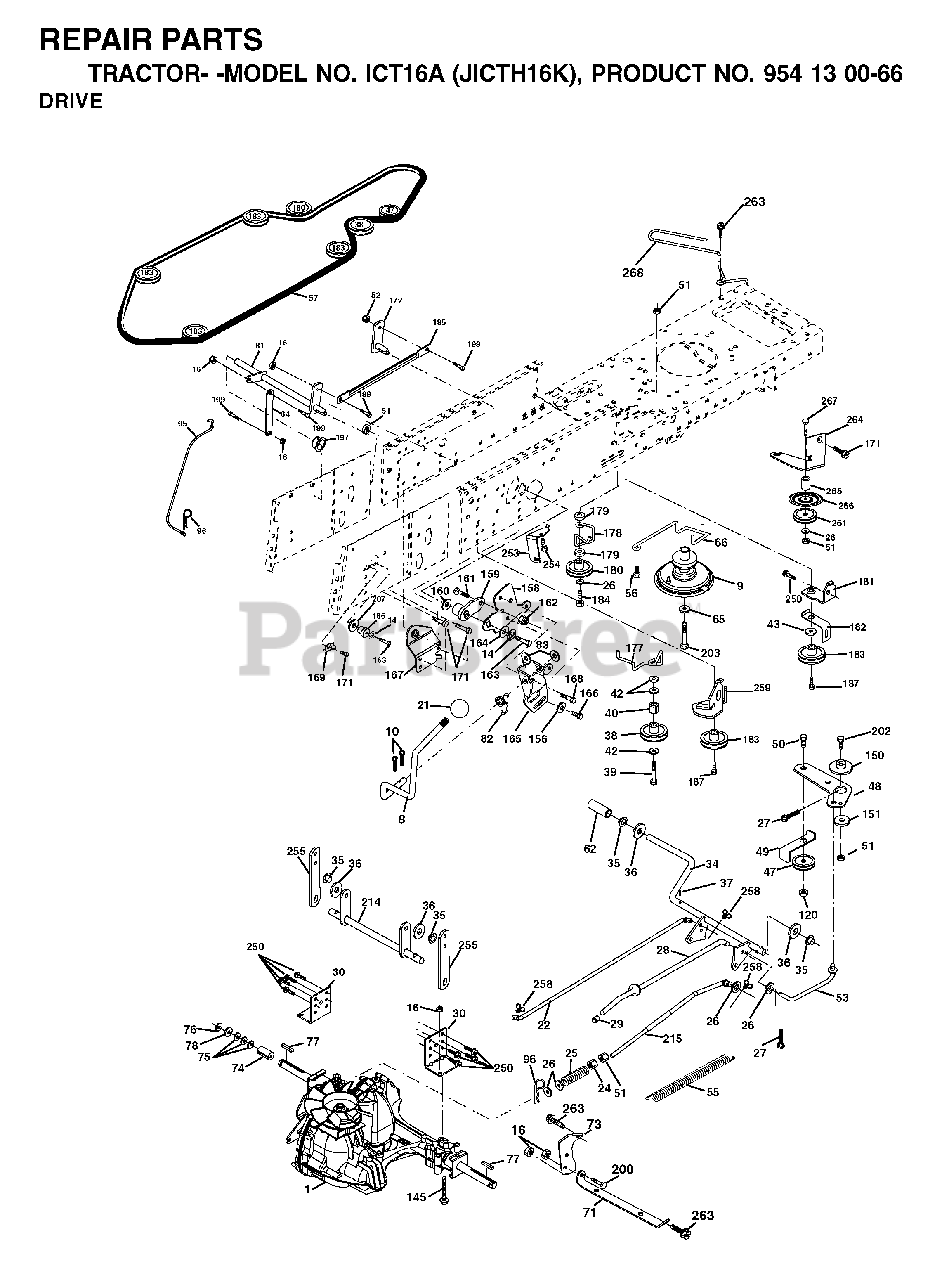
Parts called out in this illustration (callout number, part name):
8	ROD SHIFT
10	PIN COTTER
14	LOCKWASHER
16	NUT.71038.31-18.HEX.NYLOCK
21	PISTOL KNOB
24	NUT
25	SPRING ROD LT
27	COTTER PIN
28	ROD, PARKING BRAKE
29	PLUNGER CAP
30	BRKT, TRNSXLE MNT 20"
34	SHAFT, FOOT PEDAL
35	BEARING.NYLON
36	WASHER LT
37	DRIVE PIN
38	PULLEY.FLAT
42	WASHER
47	IDLER PULLEY
48	BELLCRANK, CLUTCH
49	RETAIN BELT
50	BOLT.3/8-16X1.50
51	LOCKNUT
52	LOCKNUT
53	LINK, CLUTCH LT
55	SPRING, RETURN LT
56	SCREW.3/8-16
62	PEDAL COVER T
65	LOCKWASHER
66	KEEPER BELT ENGINE
71	STRAP TORQUE LH HYDRO
73	STRAP TORQUE RH HYDRO
74	SPACER AXLE
76	E-RING LT
77	SQUARE KEY
81	SHAFT ASSY
82	SHIFT SPRING
83	WASHER
96	RETAINER M
120	NUT LOCK FLG 3/8-16 UNC
145	BOLT HEX 5/16-18 GR 5
150	BUSHING.BELLCRANK.GRD.DR
151	WASHER 12/32X2X10GA
156	WASHER.SRRTD.5/16
158	BRACKET
159	HUB
161	BOLT
162	NUT.CROWNLOCK.1/4
165	RP BRACKET
167	BRACKET
168	BOLT.SHOULDER.5/16-18X
169	PLATE.FASTENING.CROSS.SHAFT
180	PULLEY.FLAT.IDLER
184	SCREW.HXWSH.3/8
187	BOLT.5/16-18X1.25
197	NYLINER SNAP 5/8" ID
199	BOLT SHOULDER 5/16-18 UNC
200	BOLT
202	BOLT
207	WASHER NYL
250	SCREW 3/8-16X3/4
258	CLIP RETAINER
261	FLAT IDLER PULLEY
263	SCREW, 3/8-16X3/4
265	SPACER IDLER
